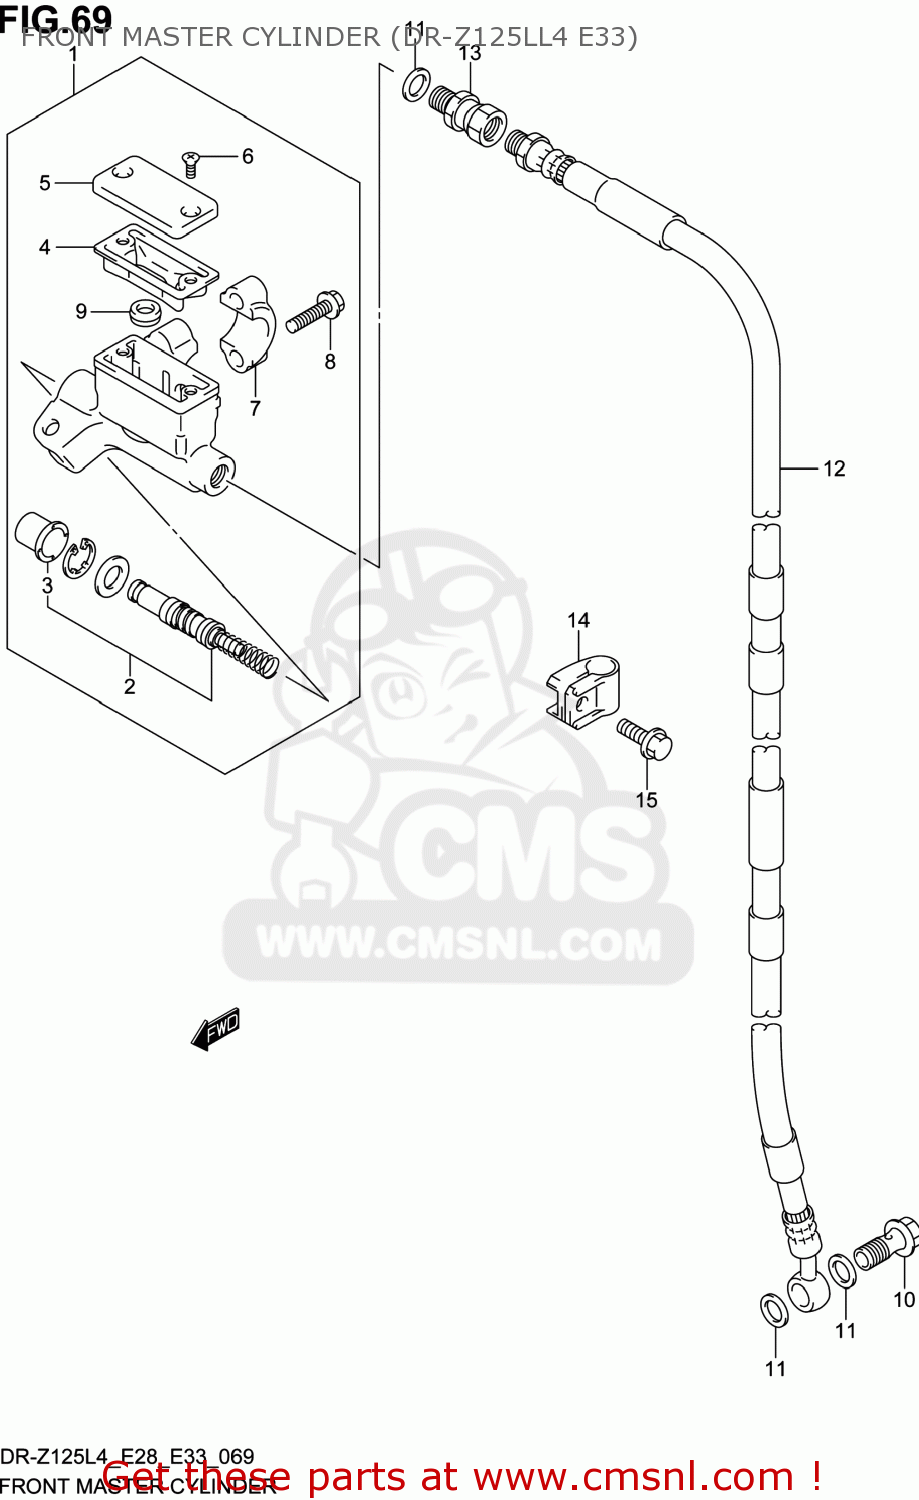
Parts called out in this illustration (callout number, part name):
1	CYLINDER ASSY,FR MASTER
2	PISTON & CUP SET
3	BOOT
4	DIAPHRAGM
5	CAP
6	SCREW
7	HOLDER
8	BOLT
9	SEPARATOR
10	BOLT UNION
11	WASHER(10X15X1.5)
12	HOSE,FR BRAKE
13	ADAPTOR,BRAKE HOSE
14	CLAMP,FR BRAKE
15	BOLT
